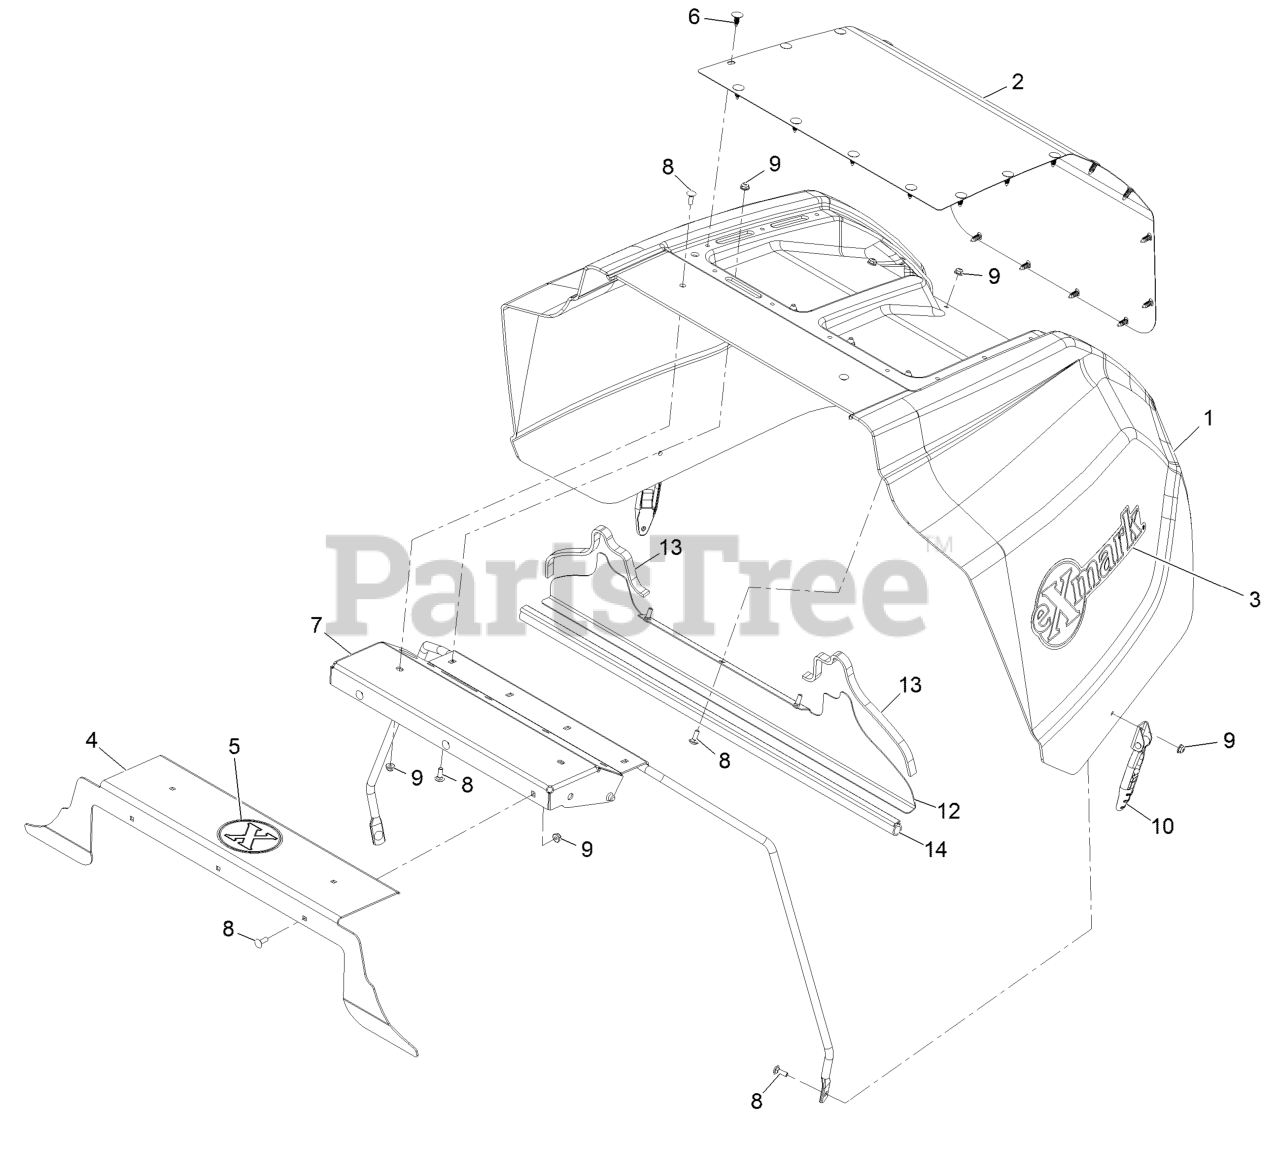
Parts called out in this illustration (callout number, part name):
1	Hood
2	Screen-Intake
3	Decal-Exmark
4	Hood-Block Off
5	Decal-X-Logo
6	Plug-Plastic
7	Support-Hood
8	Bolt-Carriage 1/4-20 X 3/4
9	Nut-Nyloc 1/4-20 Flg
10	Latch-Rubber
12	Plate-Seal
13	Seal-Foam
14	Seal-Bulb
